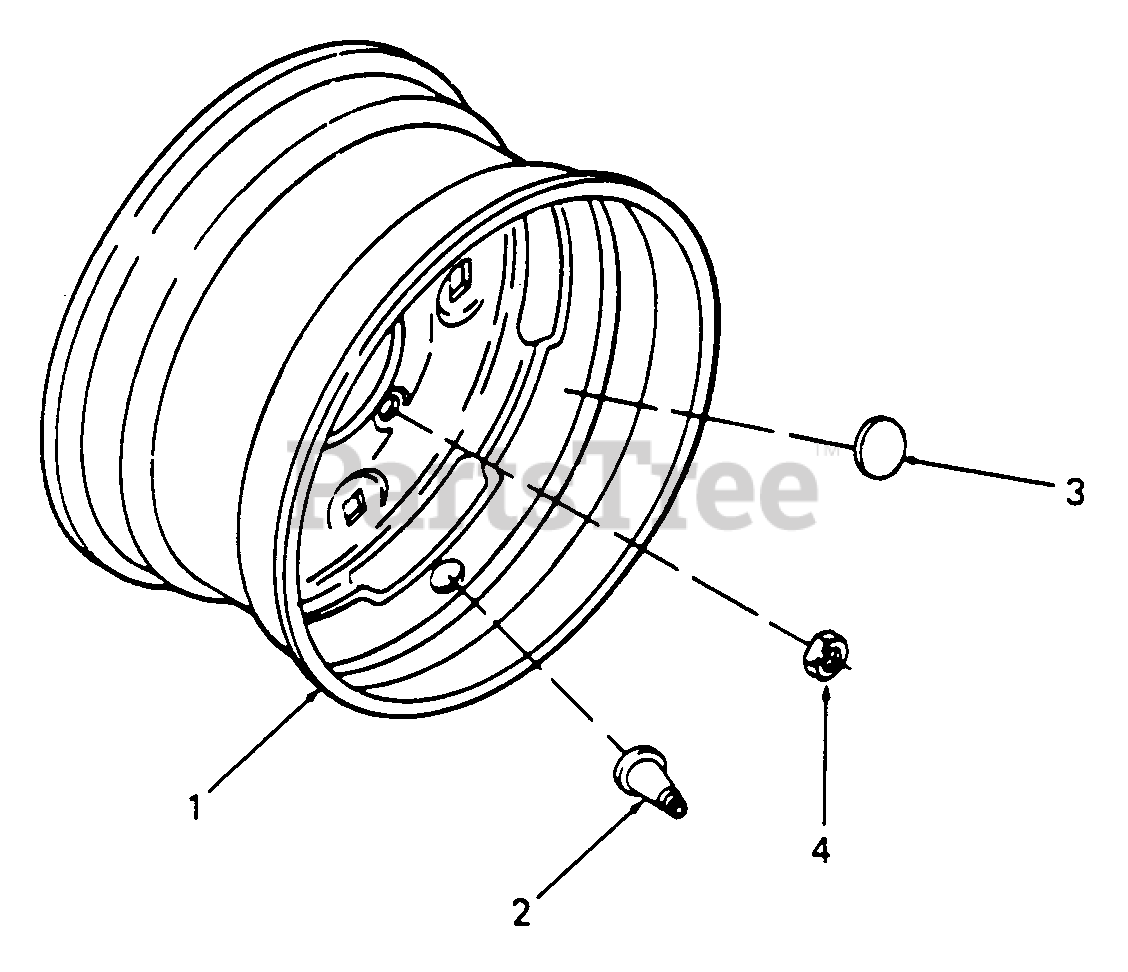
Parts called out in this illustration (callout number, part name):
2	Valve, Tubeless Air
3	Label, Inflation
4	Nut, Lug, 7/16-14
